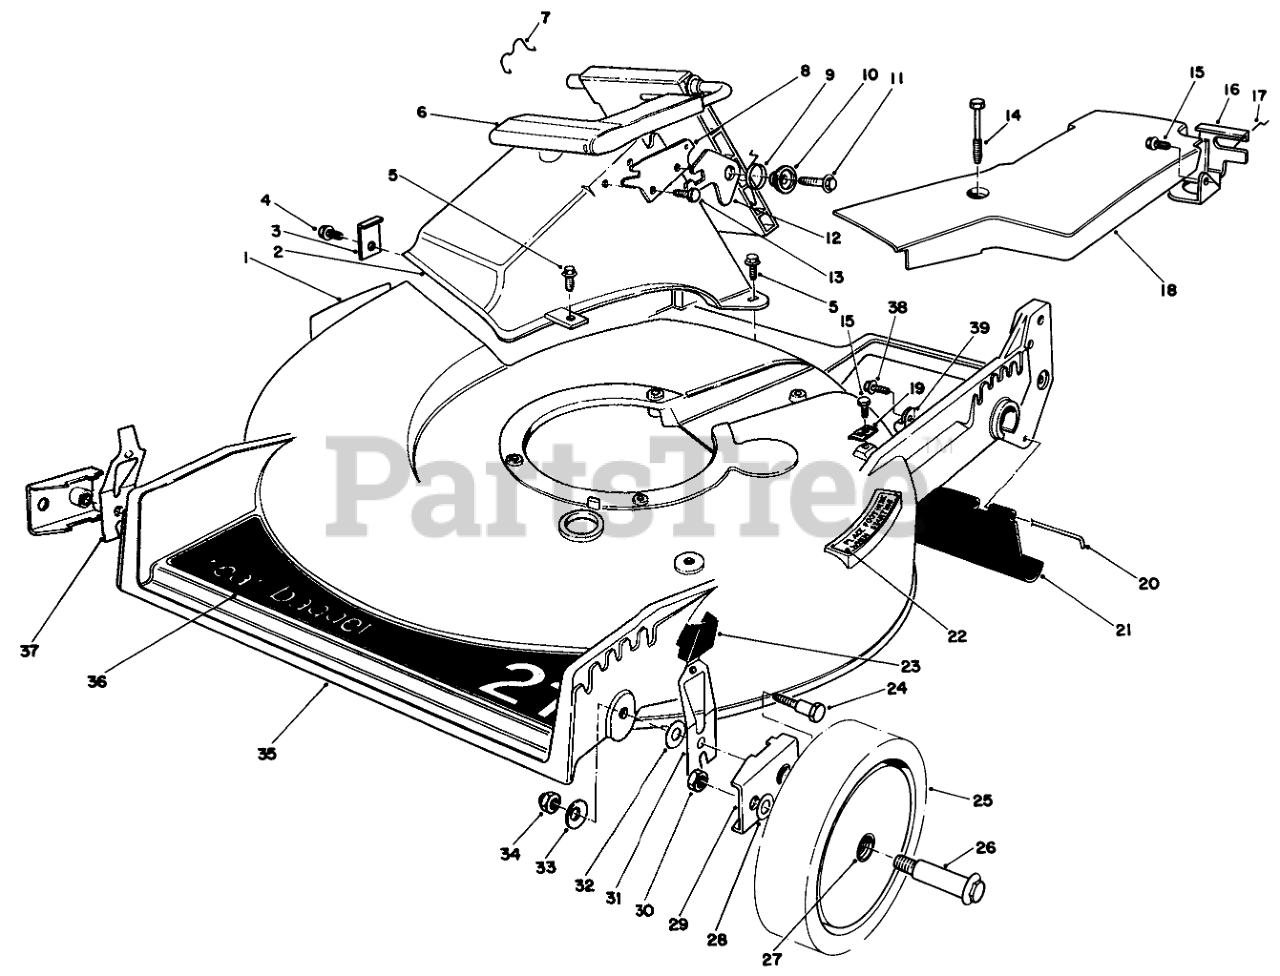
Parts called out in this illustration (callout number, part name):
1	DECAL-DANGER
2	Tunnel Discharge
3	TUNNEL CLIP
4	SCREW
5	SCREW-HWH
6	Discharge Door Assembly
7	DOOR RET SPRING
8	DOOR LATCH PLATE
9	TORSION SPRING
10	DOOR SPACER
11	SCREW-HWH
12	SAFETY LATCH
13	SCREW-PLASTITE
14	SCREW-HHFTF
15	SCREW-HWHTF
16	Bracket-Traction Adj.
17	RETAINER-CABLE
18	Belt Cover
19	CLAMP-CABLE
20	ROD-SHIELD
21	SHIELD-TRAILING
22	STEP PAD DECAL
23	KNOB-ARM
24	PIVOT SCREW
25	Wheel 8 Tire Assembly (Incl Ref. #27)
26	BOLT-WHEEL
27	BUSHING
28	WASHER
29	HP PIVOT ARM ASM
30	Nut
31	L. HP SPRING ARM ASM
32	WASHER-PIVOT
33	WASHER-BELLEVILLE
34	NUT-LOCK, NI
35	Housing-21" (Incl. Ref. #1, 5 & 22)
36	DECK DECAL
37	R HP SPRING ARM ASM
38	SCREW
39	CLAMP-CABLE
